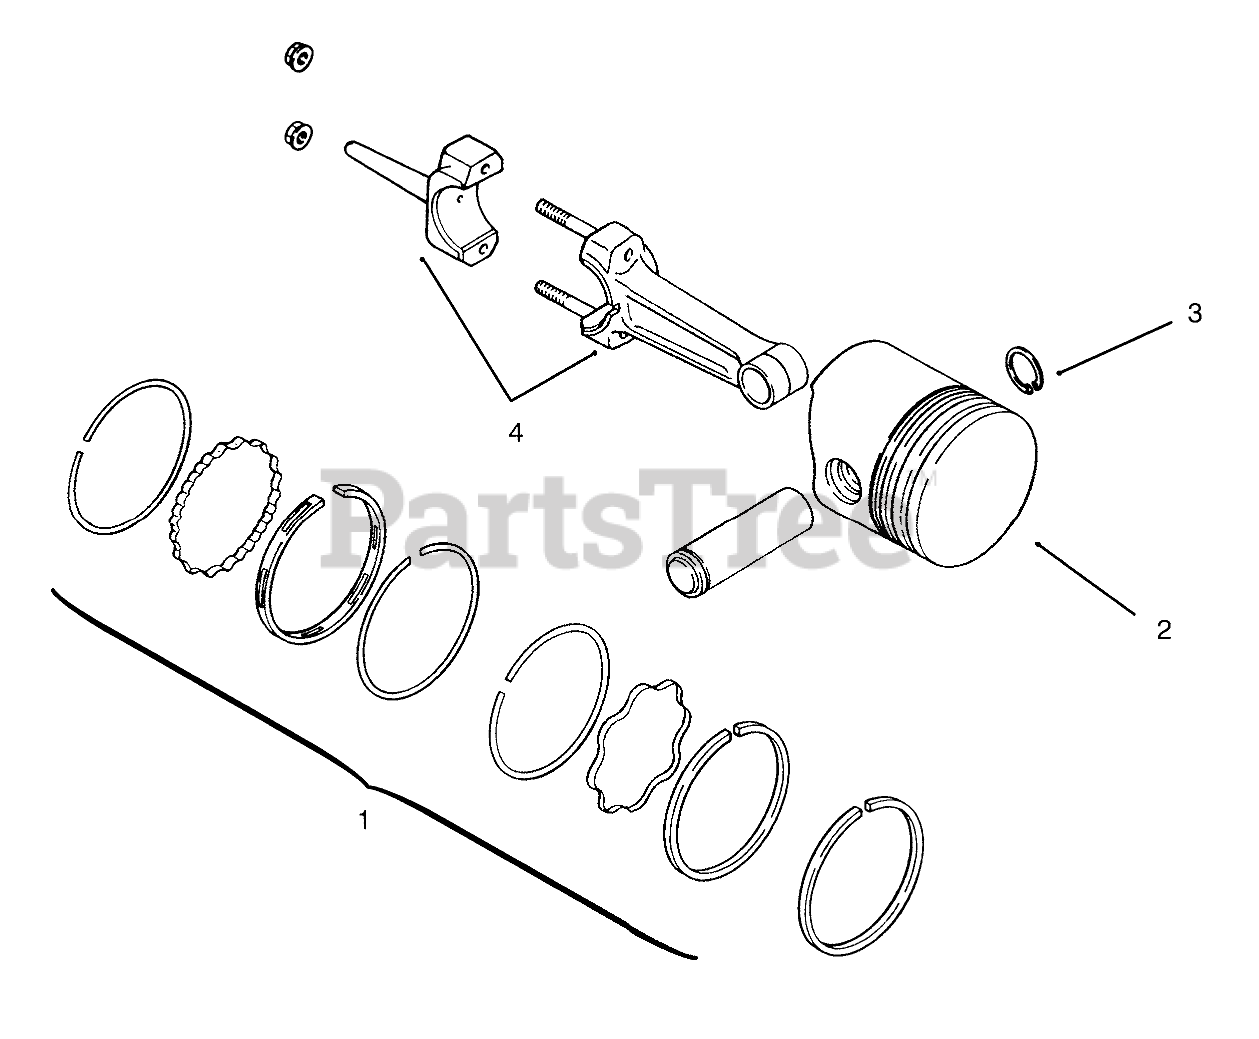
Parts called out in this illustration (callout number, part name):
1	Set-Ring, Std. &.003
2	Piston w/Ring Set Std.
3	Piston Pin Retainer
4	Rod-Connecting Std.
